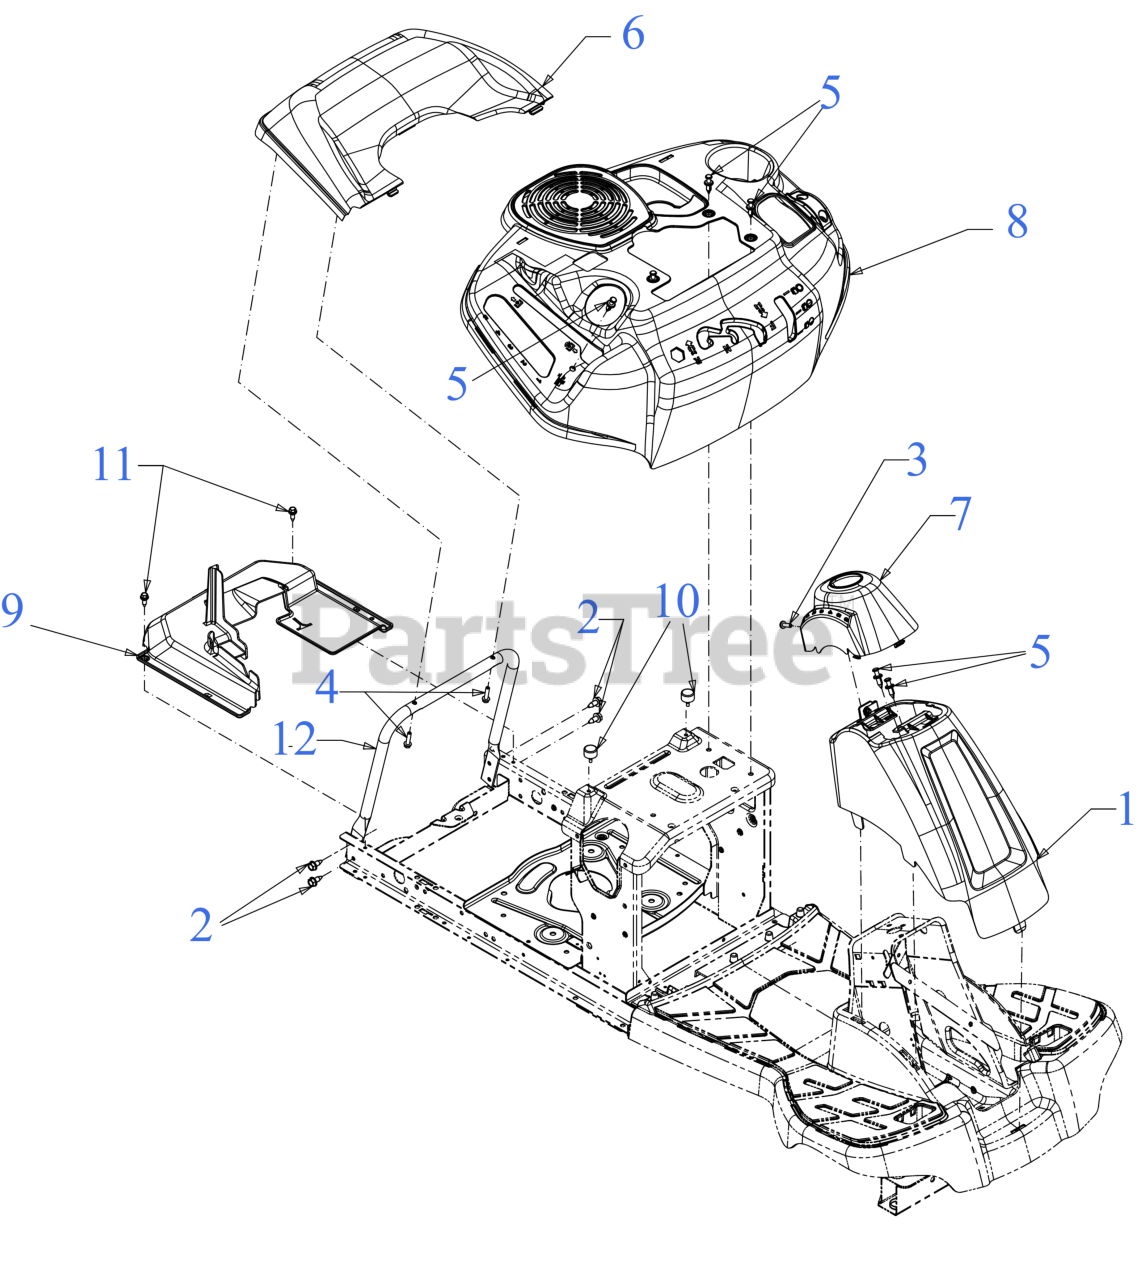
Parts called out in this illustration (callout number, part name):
1	COLUMN COVER ASSEMBLY
2	SCREW 5/16-18 x .750
3	SCREW 1/4-20X.75
4	SCREW 1/4-15 x 1.00
5	PLASTIC RIVET
7	STEERING COLUMN CAP (CUB)
9	DRIVE OVER REAR
10	BUMPER .62 DIA x .50
11	SHOULDER SCREW
